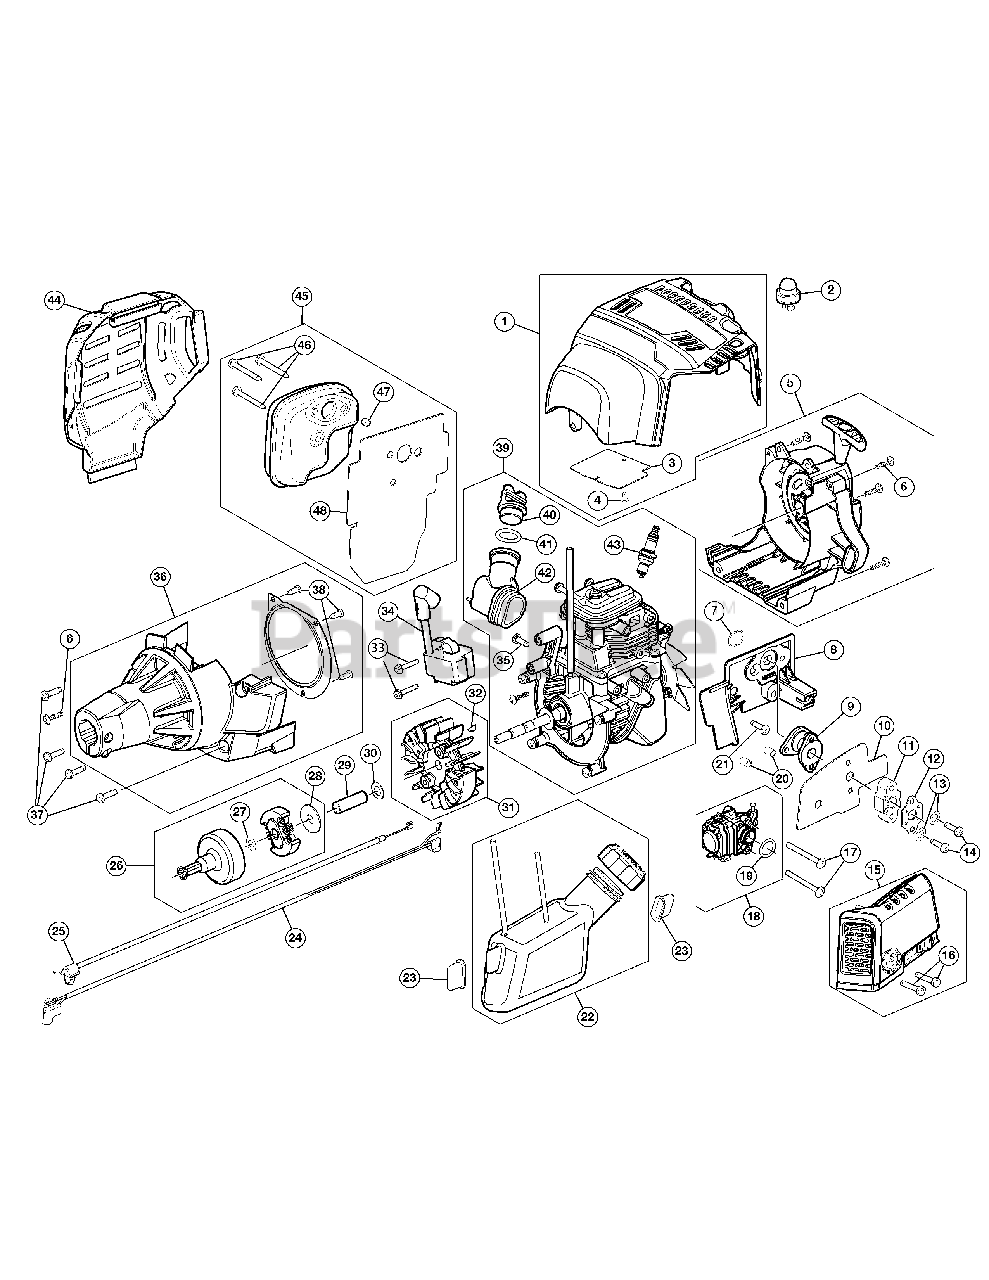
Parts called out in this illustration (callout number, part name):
1	Top Housing Assembly
2	Air Purge Primer
3	Top Cover Gasket
5	Starter Housing Assembly
8	Intake Port
9	Boot Assembly
10	Carburetor Gasket
11	Insulator
12	Insulator Gasket
14	Screw
15	Air Cleaner Assembly
18	Carburetor Assembly
20	Air Cleaner Spacer
21	Screw
22	Fuel Tank Assembly
23	Fuel Tank Pad
24	Lead Wire
25	Throttle Cable
26	Clutch Assembly
27	Thrust Washer
28	Clutch Washer
29	Power Shaft Spacer
30	Thrust Washer
31	Flywheel Assembly
34	Module Assembly
35	Screw
36	Clutch Cover Assembly
39	Shortblock Assembly
40	Oil Fill Plug
42	Oil Fill Tube
43	Spark Plug
44	Muffler Housing
45	Muffler Assembly
46	Screw
47	Air Cleaner Spacer
48	Muffler Gasket
